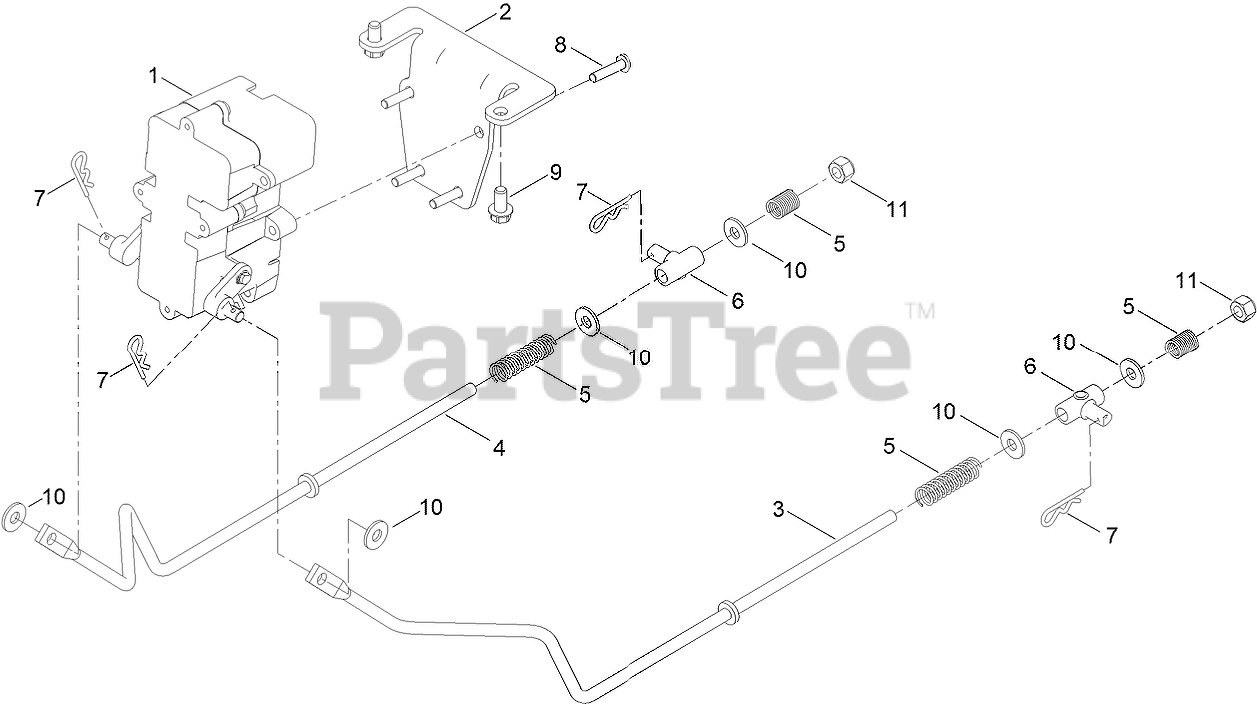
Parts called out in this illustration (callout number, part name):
1	BRAKE BOX ASM
2	BRACKET-MOUNT, BRAKE
3	ROD-BRAKE,LH
4	ROD-BRAKE,RH
5	SPRING-COMPRESSION
6	MOUNT-PIVOT
8	SCREW-PPH
9	SCREW-HWH
10	WASHER
11	NUT-LOCK, NI
